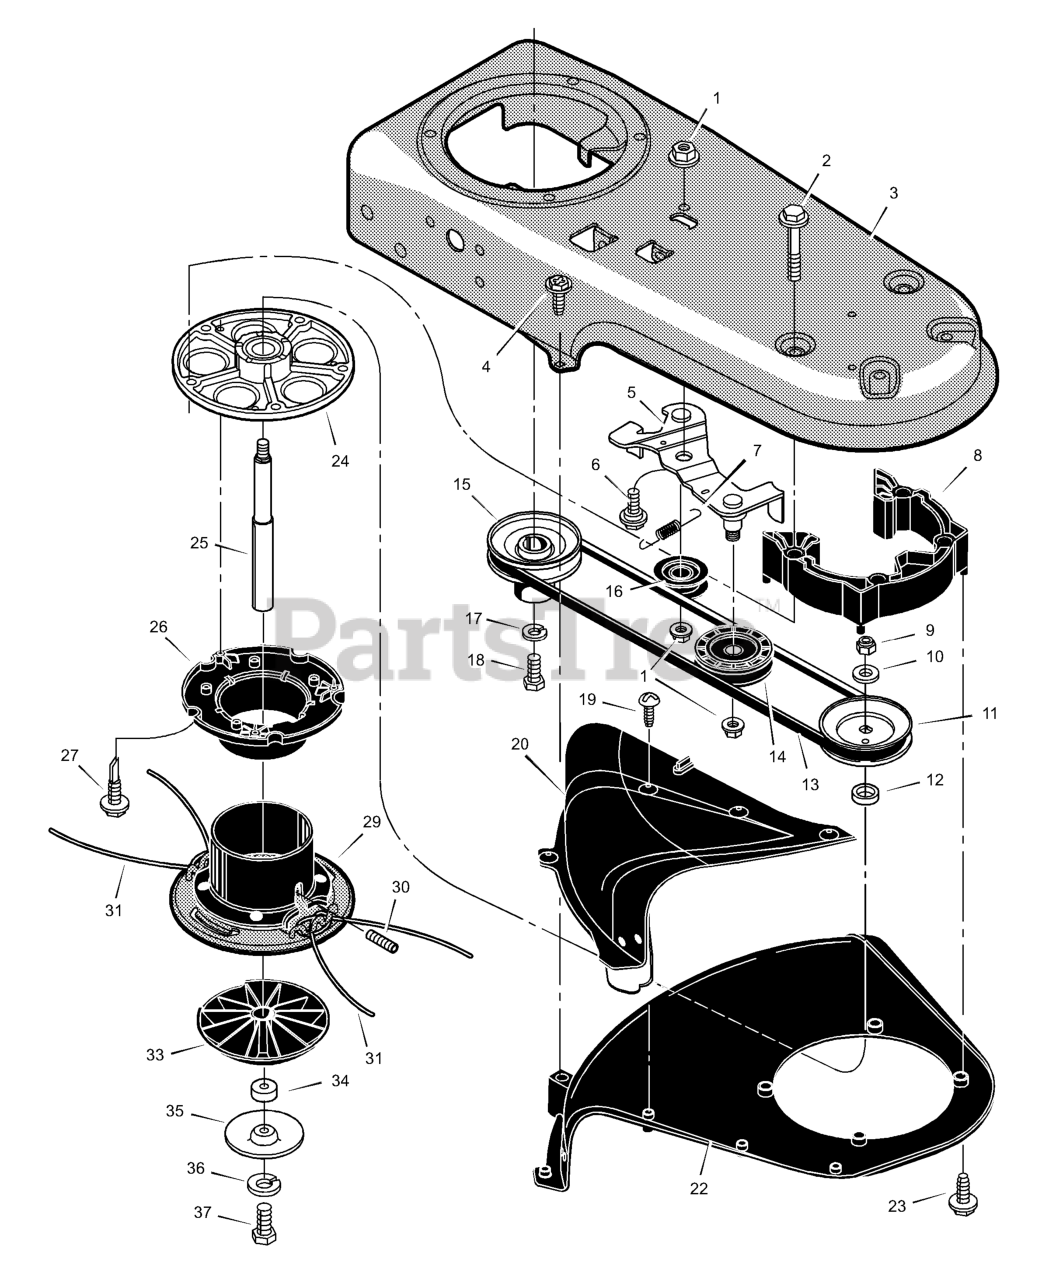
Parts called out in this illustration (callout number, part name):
2	Bolt
3	Housing, Trimmer
5	Assembly, Idler
8	Assembly, Spacer
10	Washer
11	Pulley, Cutting Head
12	Spacer
14	PULLEY, IDLER, V, 1.88
15	Pulley, Engine
16	Pulley, Idler
17	Lockwasher
20	Assembly, Guard
22	Shield, Trimmer
24	Assembly, Jackshaft Housing
25	Jackshaft
26	Wrap, Lower Weed
29	Assembly, Cutting Disc
30	Screw, Set
31	Line, Cutting
33	Guide, Height
35	Shield, Abrasion
36	Lockwasher
